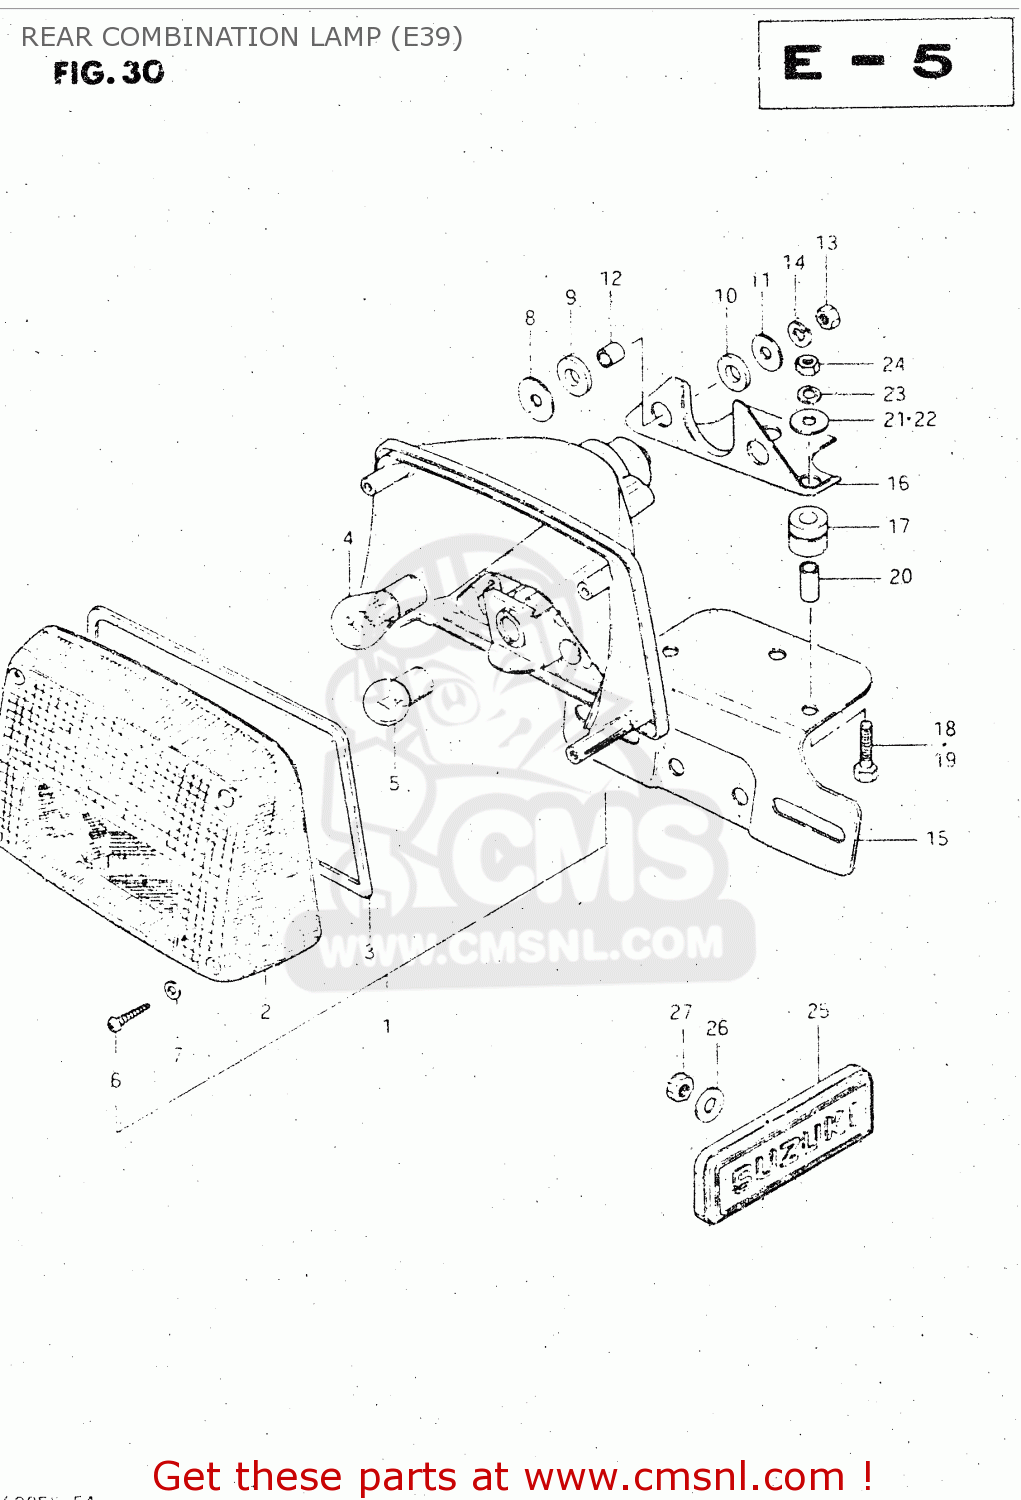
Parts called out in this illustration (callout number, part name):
1	LAMP ASSY, REAR COMBINATION
2	LENS,RR COMBI
3	GASKET (NAS)
4	BULB 12V21/5W
5	BULB
6	SCREW
7	GASKET (NAS)
8	WASHER
9	CUSHION
10	CUSHION
11	WASHER(6,5X22X1.6)
12	SPACER(6.1X9X7.5)
13	NUT
14	LOCK WASHER
15	BRACKET, LICENCE PLATE
16	BRACKET,LICENSE PLATE
17	CUSHION, BRACKET
18	BOLT
19	BOLT
20	SPACER (6.4X9X15.5)
21	WASHER
22	WASHER
23	LOCK WASHER
24	NUT
25	EMBLEM, REAR SIDE
26	WASHER
27	NUT
